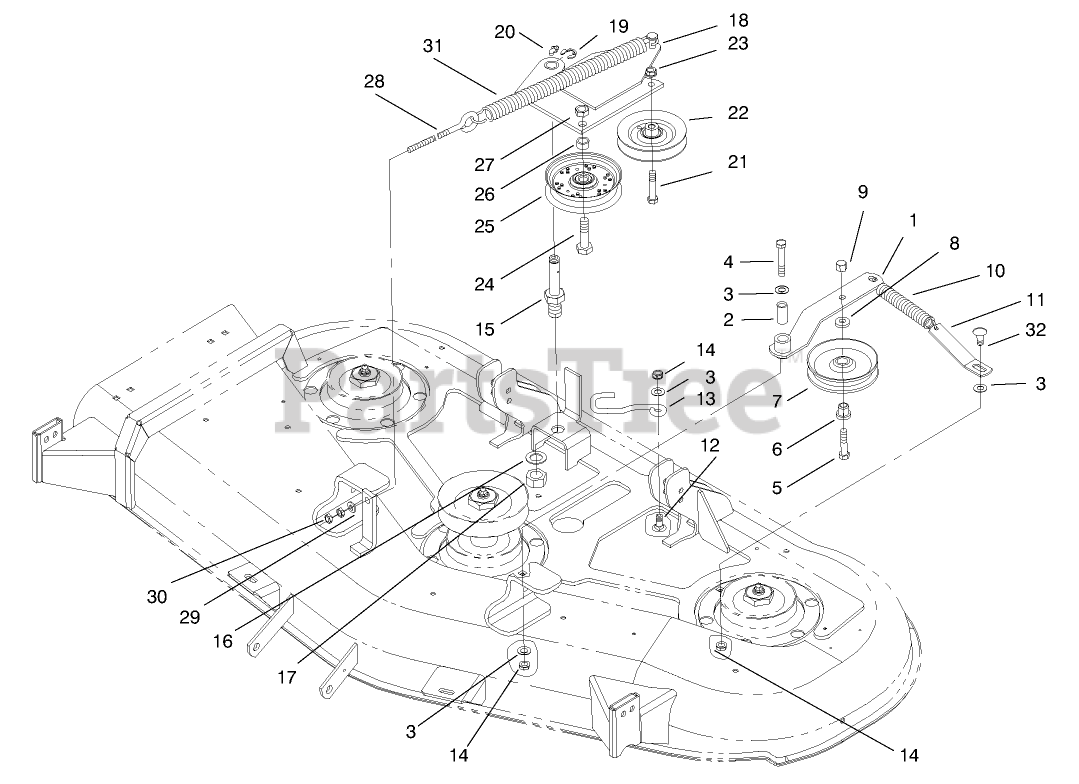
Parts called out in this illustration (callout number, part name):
1	Arm-Idler
2	SLEEVE
3	WASHER-FLAT
4	SCREW-HH
5	SCREW-HH
6	BUSHING-PULLEY
7	PULLEY-IDLER
8	WASHER-FLAT
9	NUT-HEX
10	SPRING-EXTENSION
11	PLATE-SPRING
12	SCREW-CARR
13	GUIDE-BELT
14	NUT-HF
15	SHAFT - PIVOT
16	WASHER
17	NUT-LOCK, NI
18	Idler Plate ASM
19	RETAINING RING
20	FITTING-GREASE, 90 DEG
21	SCREW-HH
22	Pulley-Idler
23	NUT-LOCK, NI
24	SCREW-HH
25	PULLEY FLAT B
26	SPACER
27	NUT-LOCK, NI
28	EYE-BOLT
29	WASHER-PLAIN
30	NUT-HEX
31	Spring-Idler
32	BOLT-CARR
